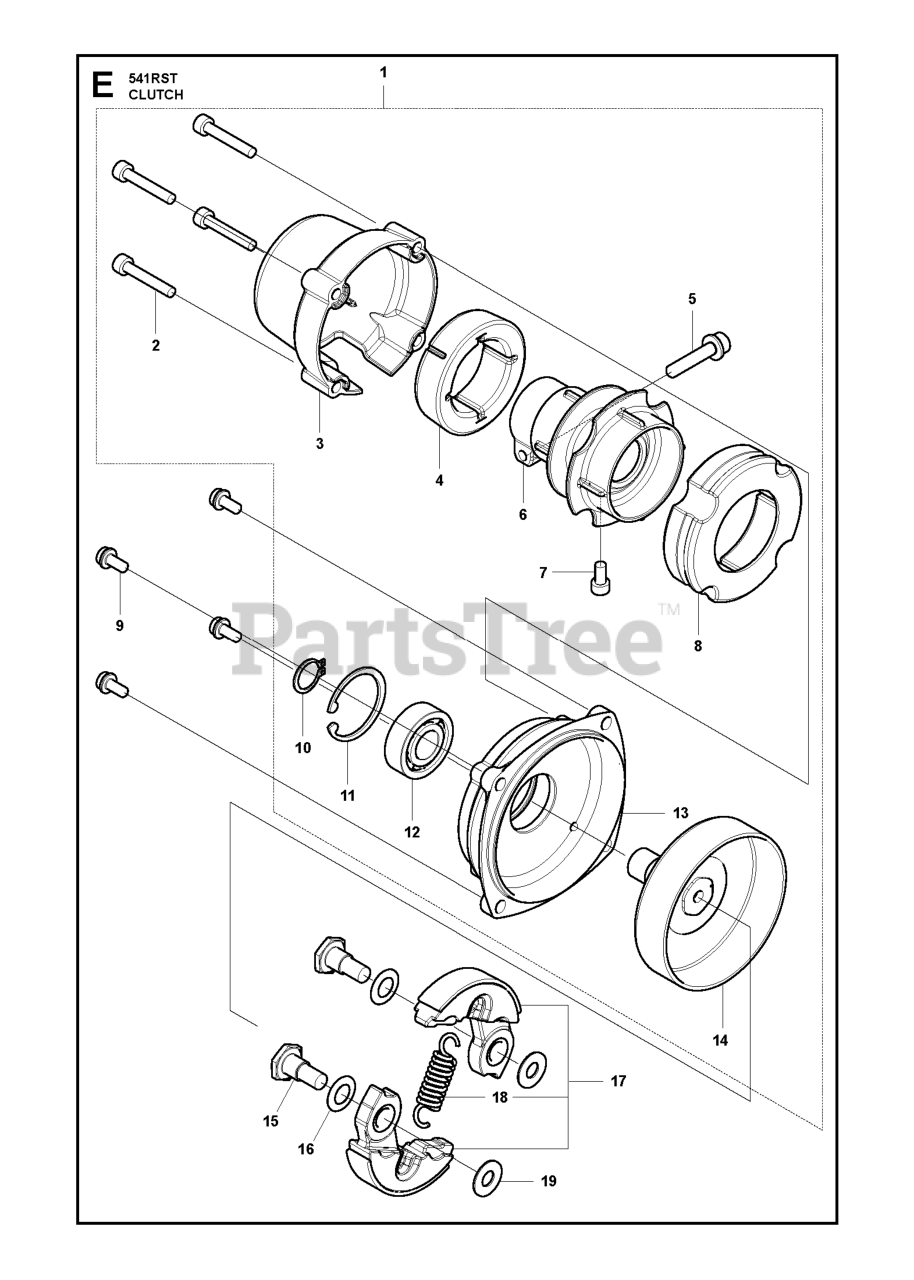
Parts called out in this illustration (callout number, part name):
7	BOLT 08
10	RING, SNAP, M15 x 1.0
12	BEARING 0600406202
14	DRUM
